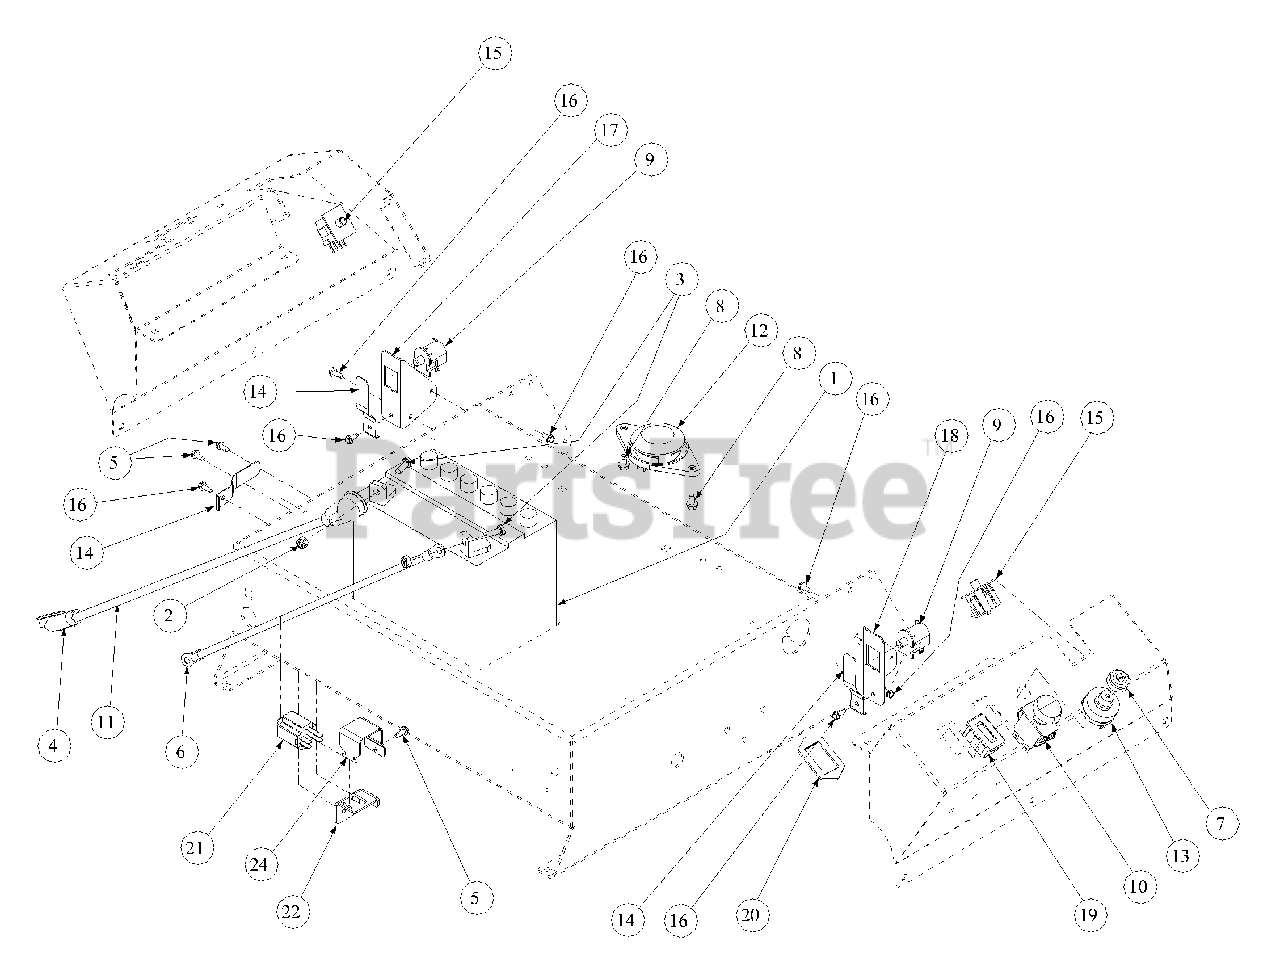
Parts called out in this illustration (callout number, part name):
1	Battery, 12V 225CCA 30Min
2	Lock Nut, Nylon Insert, 1/4-20
3	Hex Cap Screw, 1/4-20 x .75
4	Boot, 1" OD Rubber Battery-PST Red
5	Self Tapping Screw, 12-24
6	Cable, Battery, Black, 17"
7	Nut, 5/8-32, w/Cap
8	Self Tapping Screw, 1/4-20 x 1/2
9	Normally Closed Safety Switch
10	Electric PTO Switch
11	Cable, Battery, Red, 24"
12	Normally Closed Seat Switch
13	Switch, Ignition, 6 Pin
14	Safety Switch Retainer Spring
15	Neutral Switch
16	Self Tapping Screw, 10-32 x 1/2
17	Bracket, Safety Switch, Left Hand
18	Bracket, Safety Switch, Right Hand
19	Hour Meter
20	PTO Switch Bracket
21	Switch, Plunger
22	Control Housing Assembly
24	Switch, Clamp
